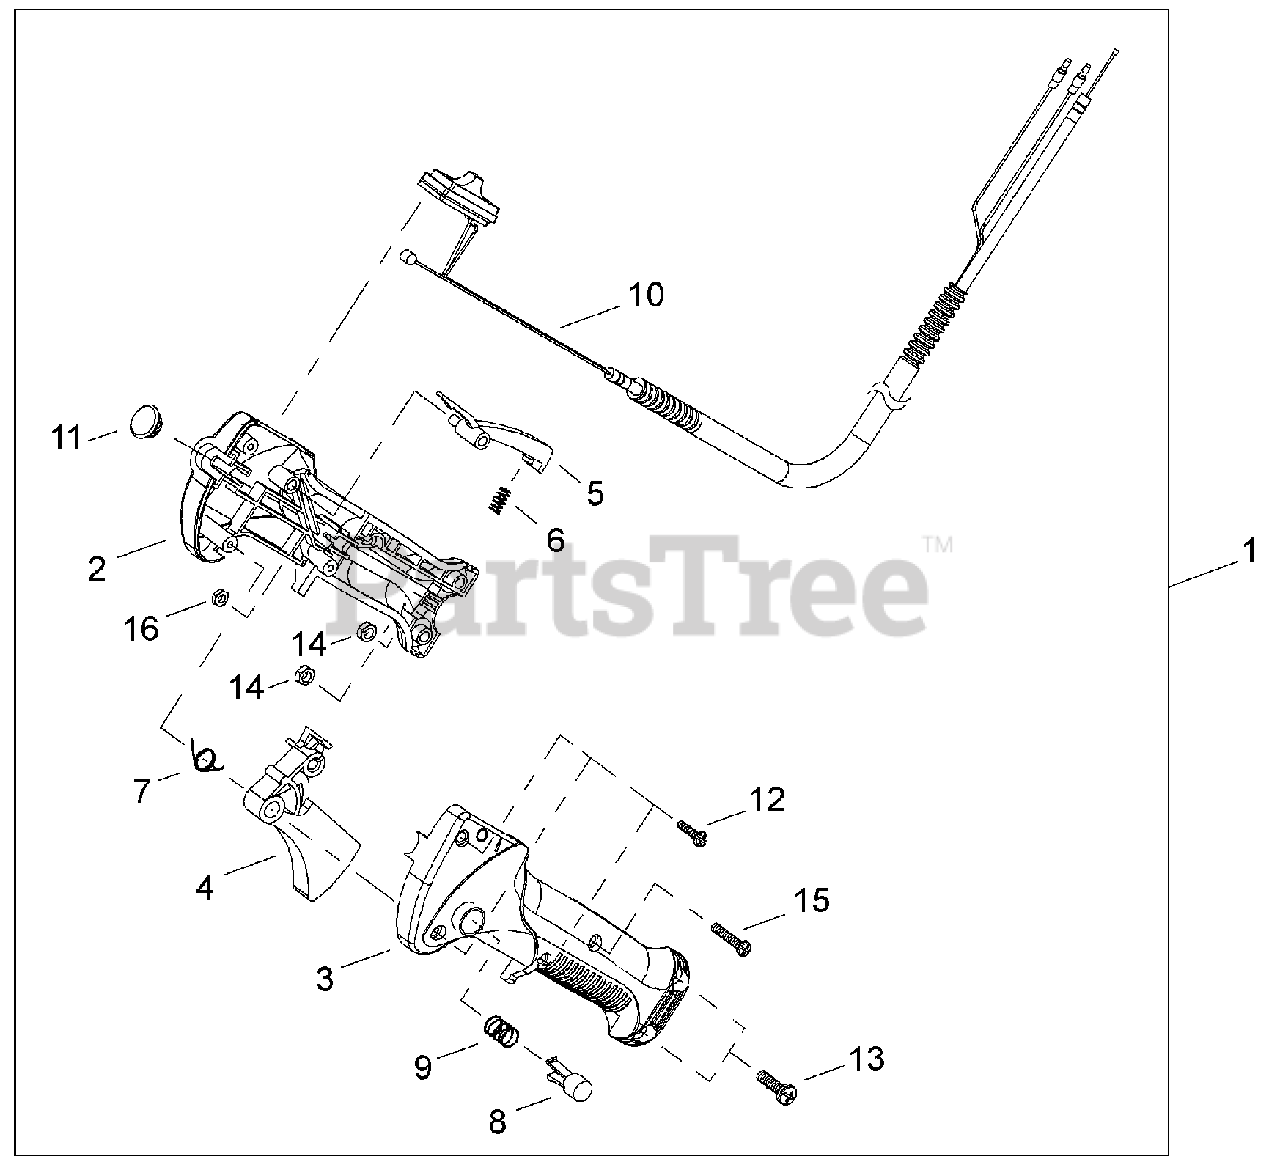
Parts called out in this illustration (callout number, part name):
1	THROTTLE CONTROL ASSY
2	HANDLE, CONTROL - RIGHT
3	HANDLE, CONTROL - LEFT
4	TRIGGER, THROTTLE
5	LEVER, TRIGGER LOCKOUT
6	SPRING
7	SPRING
8	BUTTON, THROTTLE LOCK
9	SPRING
10	THROTTLE CONTROL ASSY
11	PLUG
12	SCREW - 4X16 -- TAPPING
13	SCREW - 5X20
14	NUT - 5
15	SCREW - 4X23
16	NUT - 4
